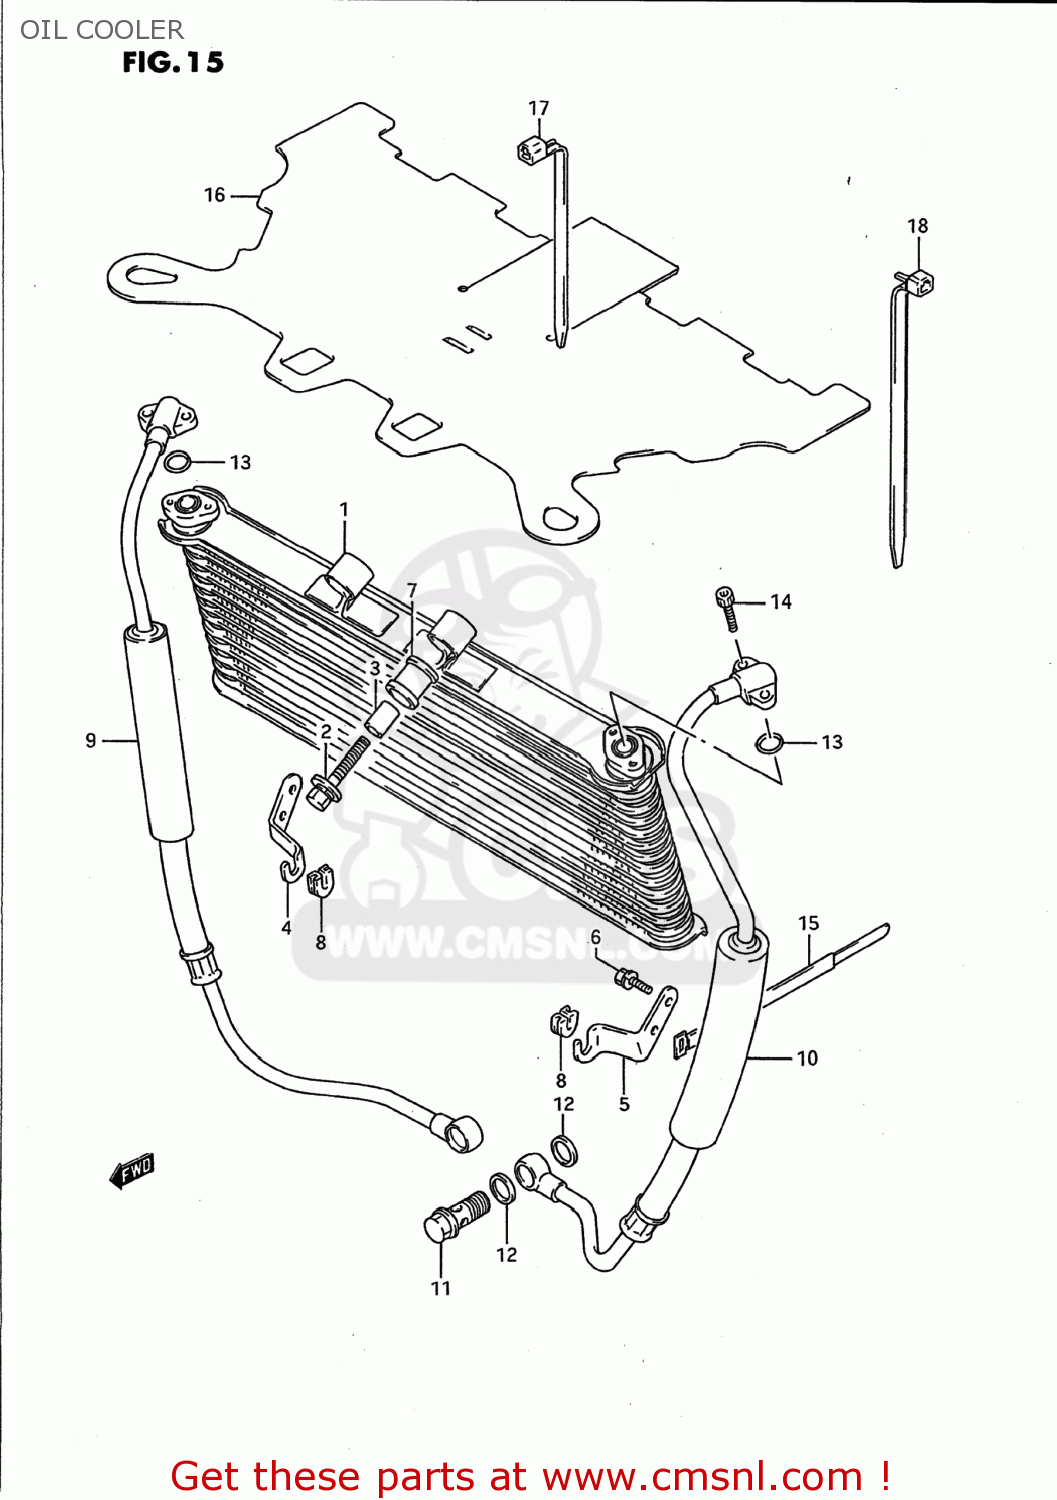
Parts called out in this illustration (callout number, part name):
1	COOLER ASSY,OIL
2	BOLT(8X40)
3	SPACER (8.8X12X24.5)
4	BRACKET,OIL COOLER,RIGHT
5	BRACKET,OIL COOLER,LEFT
6	BOLT
7	CUSHION,OIL COOLER NO.1
8	CUSHION,OIL COOLER NO.2
9	HOSE,OIL
10	HOSE,OIL
11	BOLT UNION
12	GASKET(16X22X2) (NAS)
13	O RING(D:2.4,ID:12.3)
14	BOLT
15	CLAMP(L:250)
16	PLATE,AIR GUIDE
17	CLAMP(L:165)
18	CLAMP(L:235)
